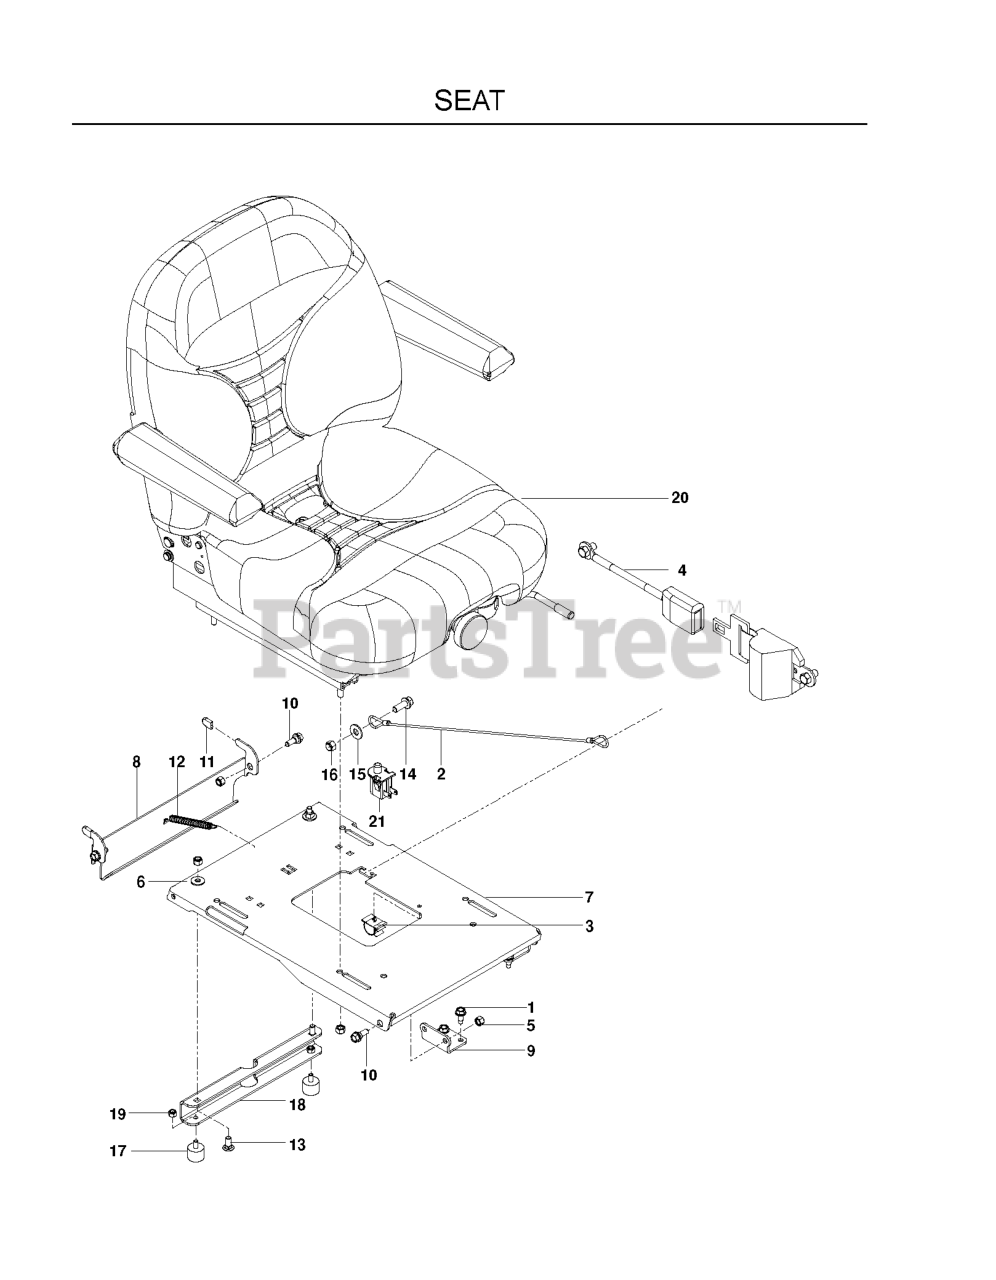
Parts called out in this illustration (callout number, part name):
1	BOLT 5/16-18 X 3/4
2	SEAT LANYARD
3	PUSH-MOUNT WIRE CLIP
4	SEAT BELT, RETRACTABLE
5	NUT 5/16 NYLOC
6	WASHER 5/16 FLAT
7	PAN, SEAT - BLACK
8	LATCH, SEAT - BLACK
9	PIVOT, SEAT PAN
10	SB 5/16-18 HEX HD GD5, BLK ZN
11	GRIP, VINYL, .09 X .495 X.75
13	BOLT 5/16C X 3/4" CARRIAGE
14	4CS 3/8C X 1 SERRATED HEAD
15	WASHER 3/8 FLAT
16	NUT 3/8-16 NYLOC
17	STUD/PLATE MOUNT
18	STANDOFF, SEAT PAN
19	NUT.1/4-20.HEX.NYLOC.ZD
20	SEAT - SUSP, NC SWITCH
21	SEAT SWITCH
